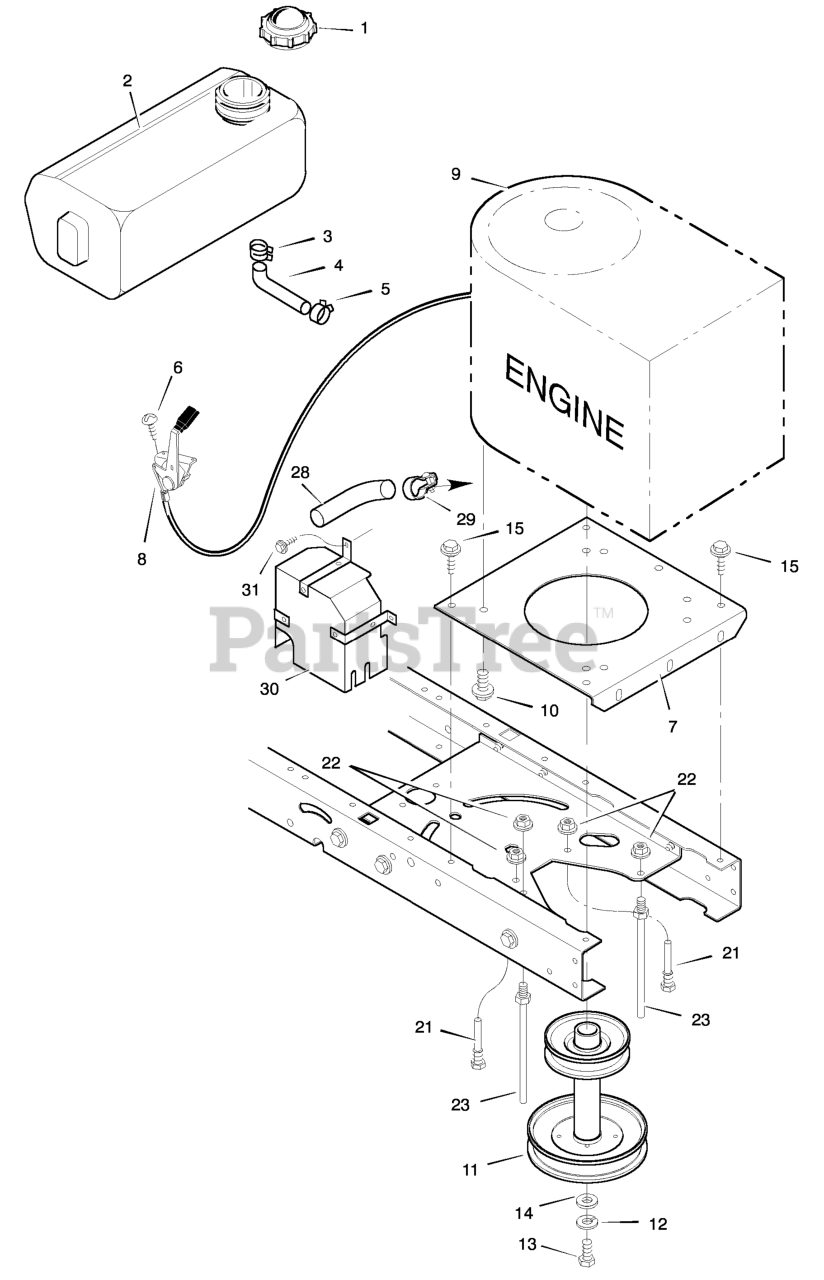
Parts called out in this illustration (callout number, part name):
1	Fuel Cap
2	Fuel Tank
3	Hose Clamp
4	Fuel Line
5	Hose Clamp
7	Plate, Engine
8	Throttle Control
9	Engine
10	Bolt, Engine Mount
11	Stack Pulley Assembly
12	Lockwasher
13	Bolt, Hex
21	Guide, Belt
22	Nut, Flange
23	Guide, Belt
28	Pipe, Exhaust
30	Shield, Heat
